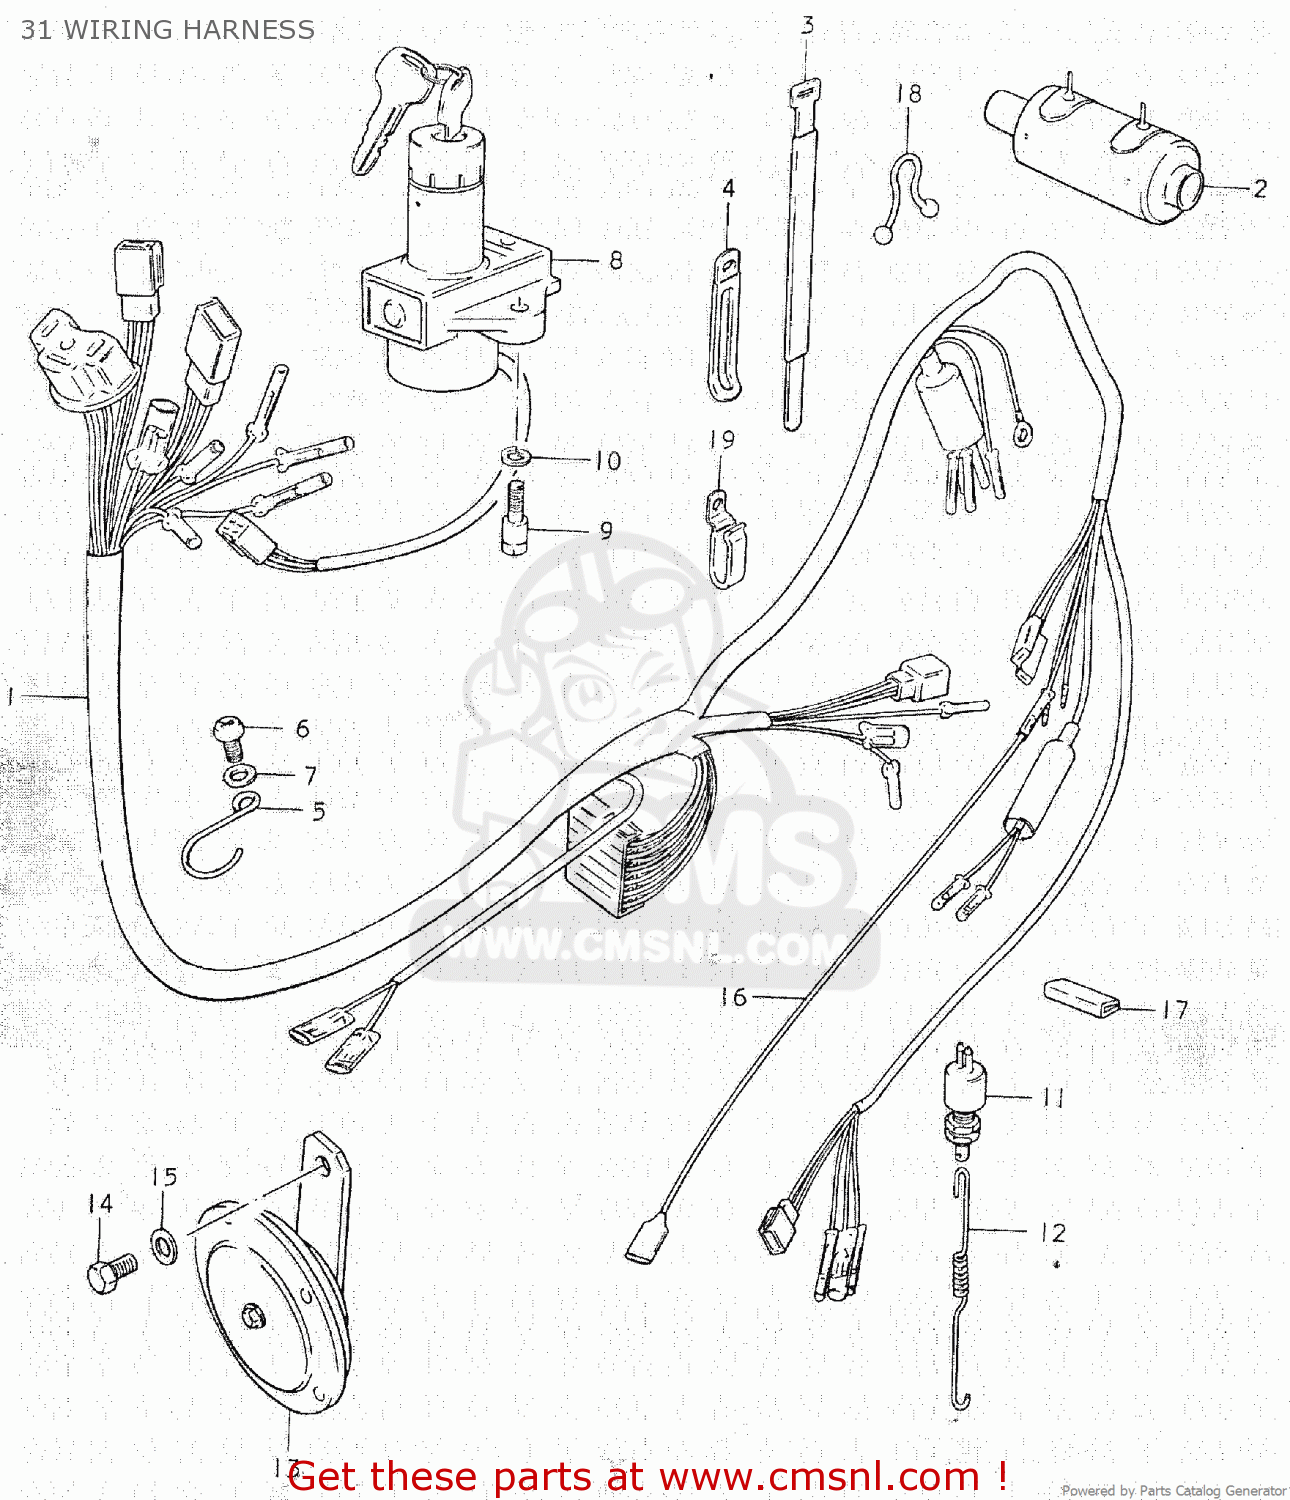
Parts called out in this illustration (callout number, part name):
1	HARNESS,WIRING
2	BOOT,WIRING HARNESS
3	CLAMP
4	CLAMP
5	GUIDE,WIRING HARNESS
6	SCREW 6X12
7	WASHER
8	LOCK ASSEMBLY,STEERING
9	BOLT
10	LOCK WASHER
11	SWITCH ASSY,BRAKE LAMP
12	SPRING
13	HORN ASSY
14	BOLT 8X12
15	WASHER
16	WIRE
17	PROTECTOR,WIRING HARNESS
18	CLAMP
19	CLAMP
